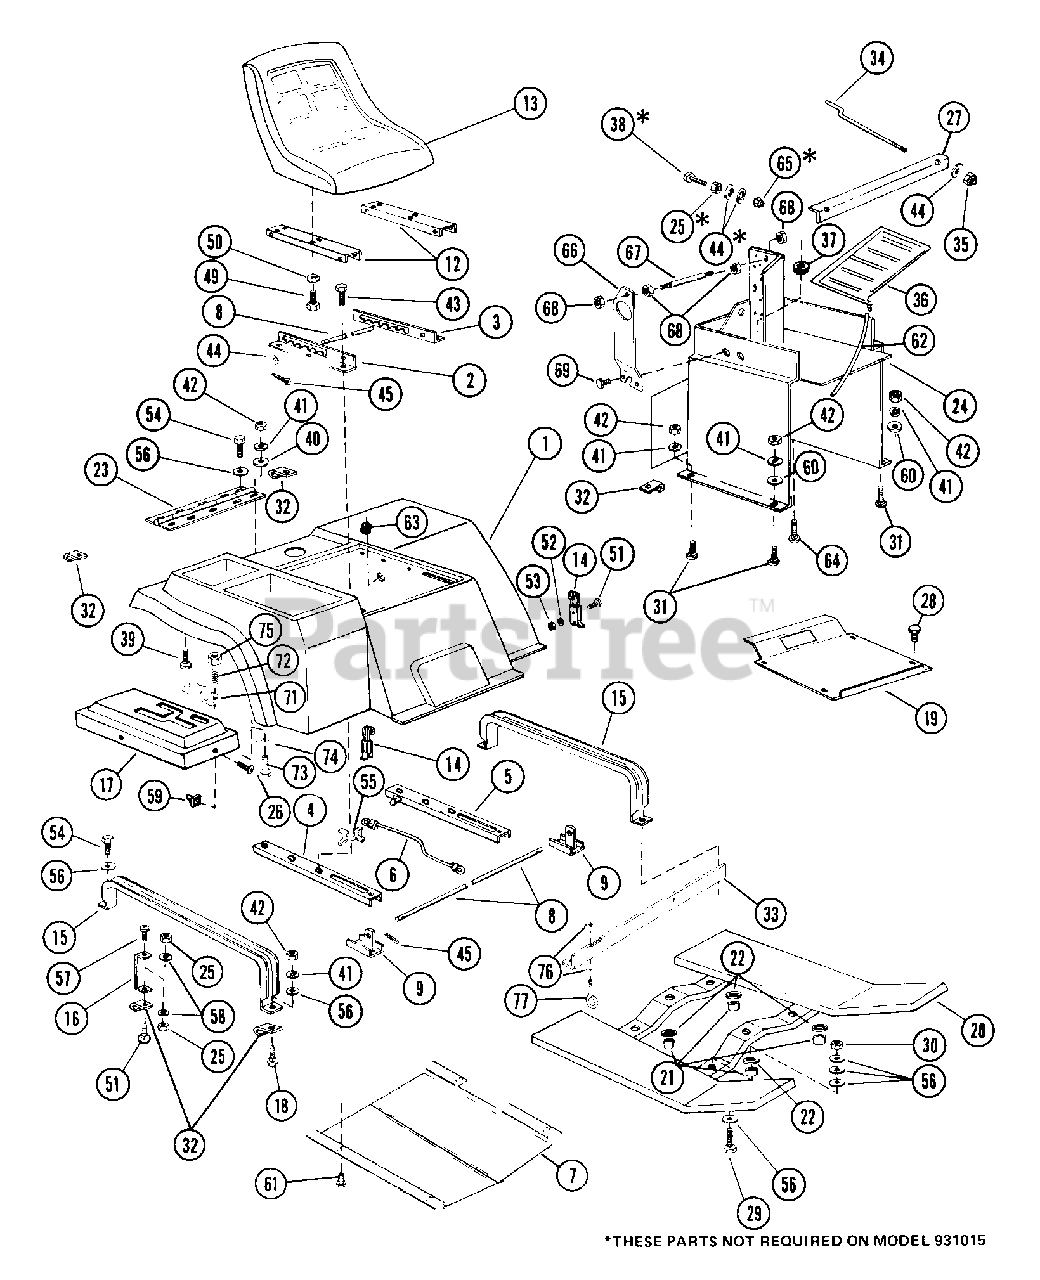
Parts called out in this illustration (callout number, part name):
1	REAR DECK
2	SEAT BRACKET R.H.
3	SEAT BRACKET L.H.
4	SEAT SUPPORT
5	SEAT SUPPORT
7	BOTTOM COVER
9	SEAT CHANNEL BRACKET
12	CHANNEL SEAT MOUNTING
12	SEAT MOUNTING CHANNEL
13	SEAT
15	CHANNEL
16	SUPPORT
17	CONSOLE ASSEMBLY
17	CONSOLE
17	CONTROL CONSOLE ASSEMBLY
18	BLT-RDHDSQNK .31-18X.75 SHT PL
19	FLOOR PLATE ASSEMBLY - HYDRO
19	FLOOR PLATE ASSEMBLY - 10 HP G
19	FLOOR PLATE ASSEMBLY - 14 HP G
20	RUNNING BOARD
21	SPACER .318X.430X.375
22	GROMMET .438ID X .688 OD
23	HINGE-2" X 12.88 YWZC
24	DASH SUPPORT ASSEMBLY
24	DASH SUPPORT SERVICE ASSEMBLY
25	NUT-HEX .250-20 PL
26	SCR-TAP 10-12X.50 CRPH PL A
27	BATTERY TIE DOWN
28	BLT-SERHFWH .25-20X.50 PL
29	BLT-HEX .31-18X1.25 PL GR2
30	NUT-LK .312-18 GR A PL
31	BLT-RDHDSQNK .31-18X.75 GR5 PL
32	J-CLAMP
33	BRACE
34	TIE DOWN ROD
35	NUT-LK TOP .250-20 PL
36	TRAY - BATTERY
36	PAD
36	BATTERY TRAY
37	GROMMET 1.0ID X 1.38 OD
38	BLT-HEX .25-20X1.50 GR5
39	SCR-MCH .31-18X.75 TSKBHD PL
40	WSHR-FL-STL.344X.688X.065PL
41	WSHR-LK .312X.097 PL HVY
42	NUT-HEX .312-18
43	SCR-TAP 10-16X.50 HWH PL AB
44	WSHR-FL-STL.281X.62X.065 PL
45	PIN-COTR .06X.50
49	BLT-HEX .38-16X.75 PL GR2
50	WSHR-LK .375X.094 MED PL
51	SCR-MCH 10-24X.50 SLRH PL
52	WSHR-LK-EXT #10 ID X .022
53	NUT 10-32 PL
54	SCR-TAP .312-18X.75 HWH PL TR
55	X WASHER
56	WSHR-FL-STL .38X.875X.083 PL
57	SCR-MCH .25-20X.75 SLTR PL
58	WSHR-LK .250X.077 HVY PL
59	PLASTIC GROMMET
59	NUT-SPEED U TYPE 10A
60	WSHR-FL-STL.344X.688X.065PL
61	BLT-SERHFWH .25-20X.50 PL
62	1 IN OF 00910000 HOSE
63	GROMMET
64	BLT-RDHDSQNK .31-18X1.00 PL
65	NUT-HEX JAM .25-20 YWZC
66	HOUR METER MOUNTING PLATE
67	BRACE ROD
68	NUT-LK-FLG .250-20 PL
69	SCR-TAP .250-20X.50 HXSLHDPL
71	LOCKOUT STOP
72	SG-COMP .045X.50X1.187
73	BLT-HEX .38-16X1.50 PL GR2
74	WSHR-FL-STL .438X1.0X.083 PL
75	NUT-HEX .375-16
76	NUT-LK-CTR .250-20 PL
77	ROD HANGER EYEBOLT
